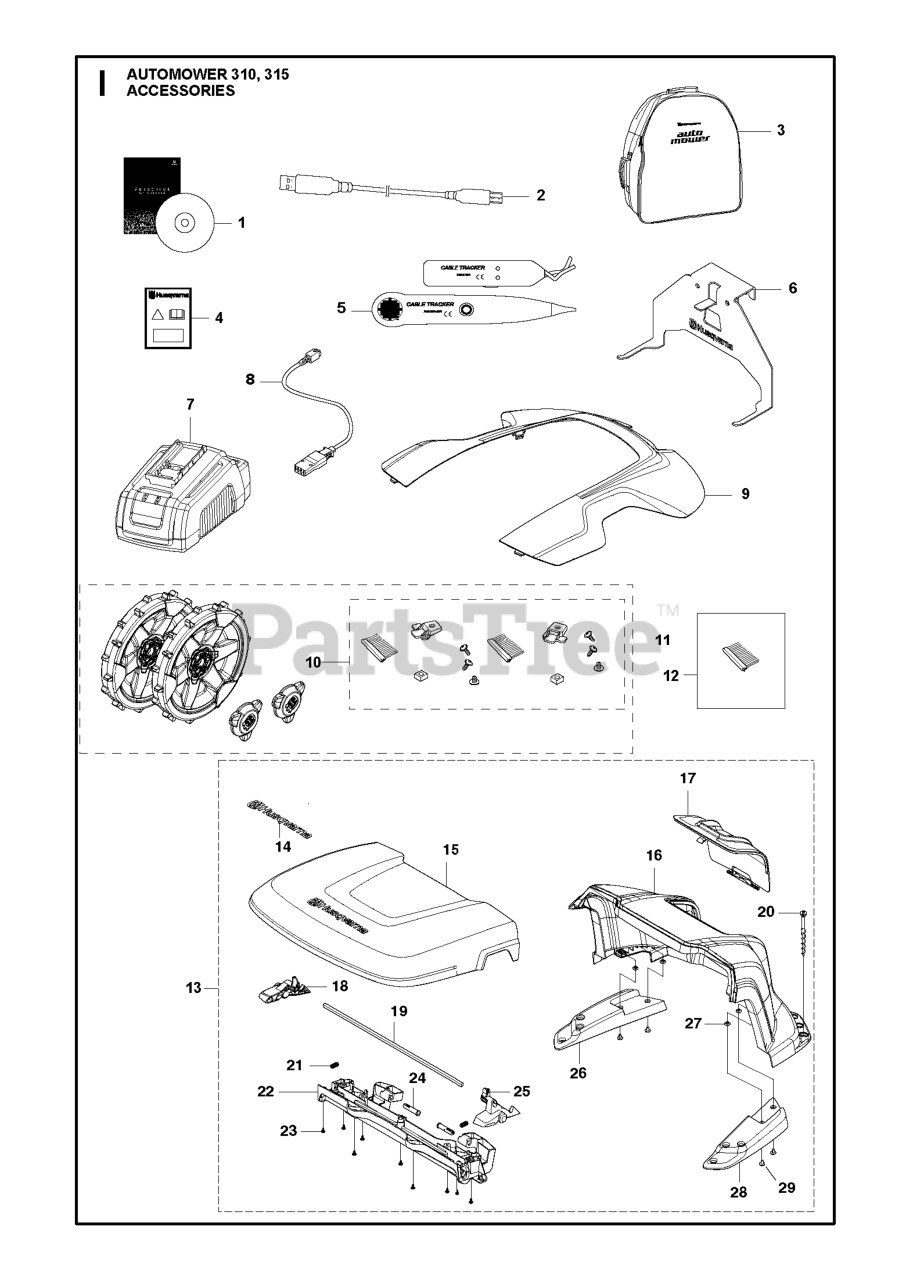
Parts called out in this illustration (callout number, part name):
1	DVD AUTOCHECK EXP SERVICE
2	CABLE WHITE ALT GREY
4	LABEL WARRANTY SEAL KIT 10 PK
5	TEST EQUIPMENT
6	315 WALL HANGER
7	CHARGER BATTERY TEST
8	CABLE ASSY QUICK CHARGER
9	ORANGE COVER
9	WHITE COVER
9	GREY COVER
10	WHEEL BRUSH KIT 315
11	WHEEL KIT AM310/315. HEAVY REA
12	BRUSH KIT - ONLY BRUSHES 6 PCS
13	HOUSE KIT FOR 315
14	DECAL.HUSQVARNA.210MM
15	COVER LID 315
16	COVER BASE P15
18	HANDLE RELEASE LEFT
20	SCREW KIT CS
21	SPRING SPRING CAP
23	SCREW 14MM
25	HANDLE RELEASE RIGHT
26	SUPPORT BASE LEFT
28	SUPPORT BASE RIGHT
29	SCREW IHPANM M6X25 4.6 ZP-BC
